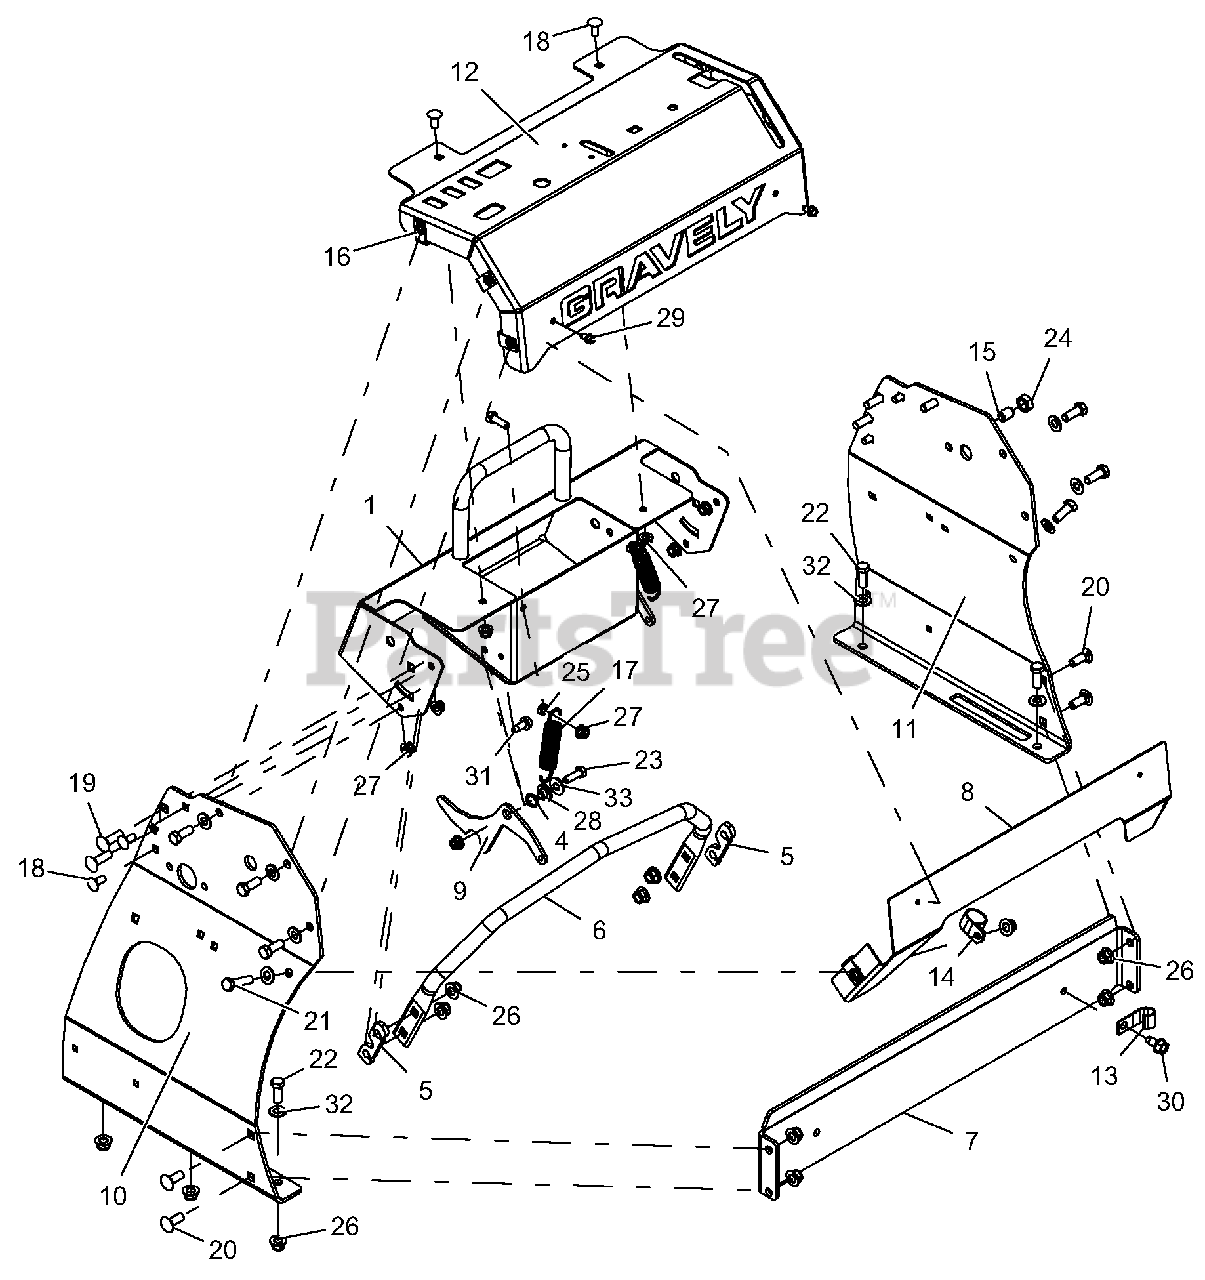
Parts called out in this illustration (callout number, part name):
1	WLDMT, CONTROL PANEL, PRO-STANCE
4	WAVE WASHER .531 x .781 x .125 FH
5	SHIM, BAR 5 DEG SPEED - BLACK
6	STOP, FORWARD STEERING
7	STIFFENER, TOWER
8	PLATE, FRONT BACKER
9	LATCH, PAD MOUNT
10	PANEL, TOWER RH, PRO-STANCE
11	PANEL, PROSTANCE LH TOWER
12	PANEL, CONTROL - PRO-STANCE
14	CLAMP, CUSHIONED STEEL REV
15	BALL SPRING PLUNGER, .500-13
16	NUT, RTNR .375-16 x .37
17	SPRG, EXTENSION
18	BLT-RDHDSQNK .31-18 x .75 G5 YWZC
19	BLT-RDHDSQNK .38-16 x 1.25 G5 YWZC
20	BLT-RDHDSQNK .38-16 x 1.00 G5 YWZC
21	BLT-HEX .38-16 x 1.50 GR5 YWZC
22	BLT-HEX .38-16 x 1.00 GR5 YWZC
23	BLT-HEX .31-18 x 1.00 GR5 YWZC
24	NUT, JAM .500-13 YWZC
25	@NUT-LK-CTR-JAM .31-18 YWZC
26	NUT-LK-NYL-FLG .38-16 YWZC
27	NUT-LK-NYL-FLG .31-18 YWZC
28	BSHG, FLG .32 x .500 .344 x .880
29	SCR-TAP .25-20 x .50 HWH TR YWZ
30	SCR-TAP .38-16 x .75 HWH TR YWZ
31	SCR-TAP .31-18 x .75 HWH TR YWZ
32	WSHR-FL-STL .406 x .812 x .065 YWZ
33	WSHR-FL-STL .38 x .875 x .083 YWZC
